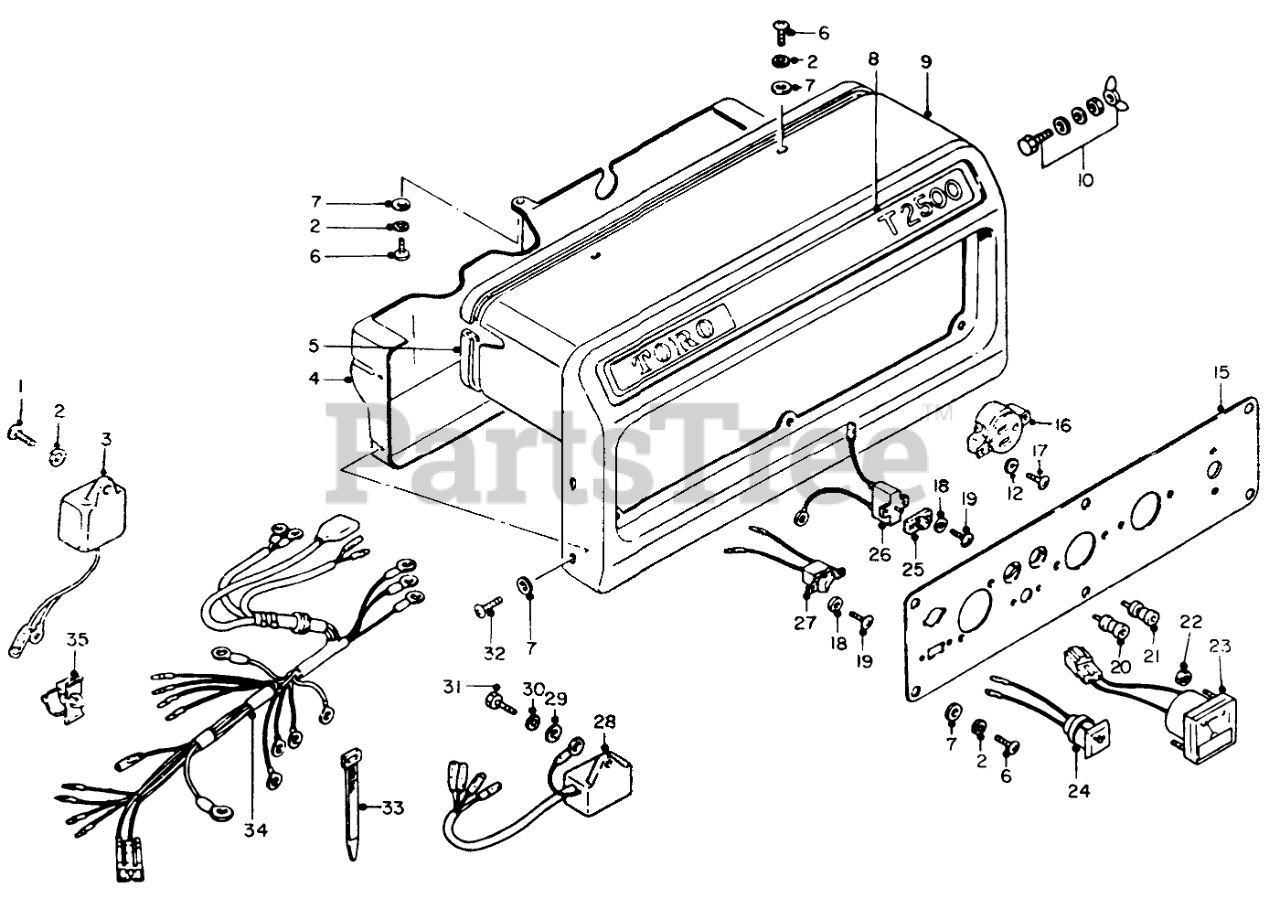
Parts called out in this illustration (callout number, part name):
1	Screw
2	Washer
3	X-STR MAG UNIT
4	Panel-Rear
6	SCREW
7	WASHER
8	Emblem-Toro T2500
9	Panel-Control
10	GROUND TERMINAL
12	Washer
15	Plate-Panel
16	Receptacle
17	Screw
18	Washer
19	Screw
20	TERMINAL-
23	Meter-Voltage
26	Circuit Breaker DC
27	Switch
28	OIL LEVEL UNIT
29	Washer
30	LOCKWASHER
32	Screw
33	Clamp
34	Harness-Control
35	Clamp
